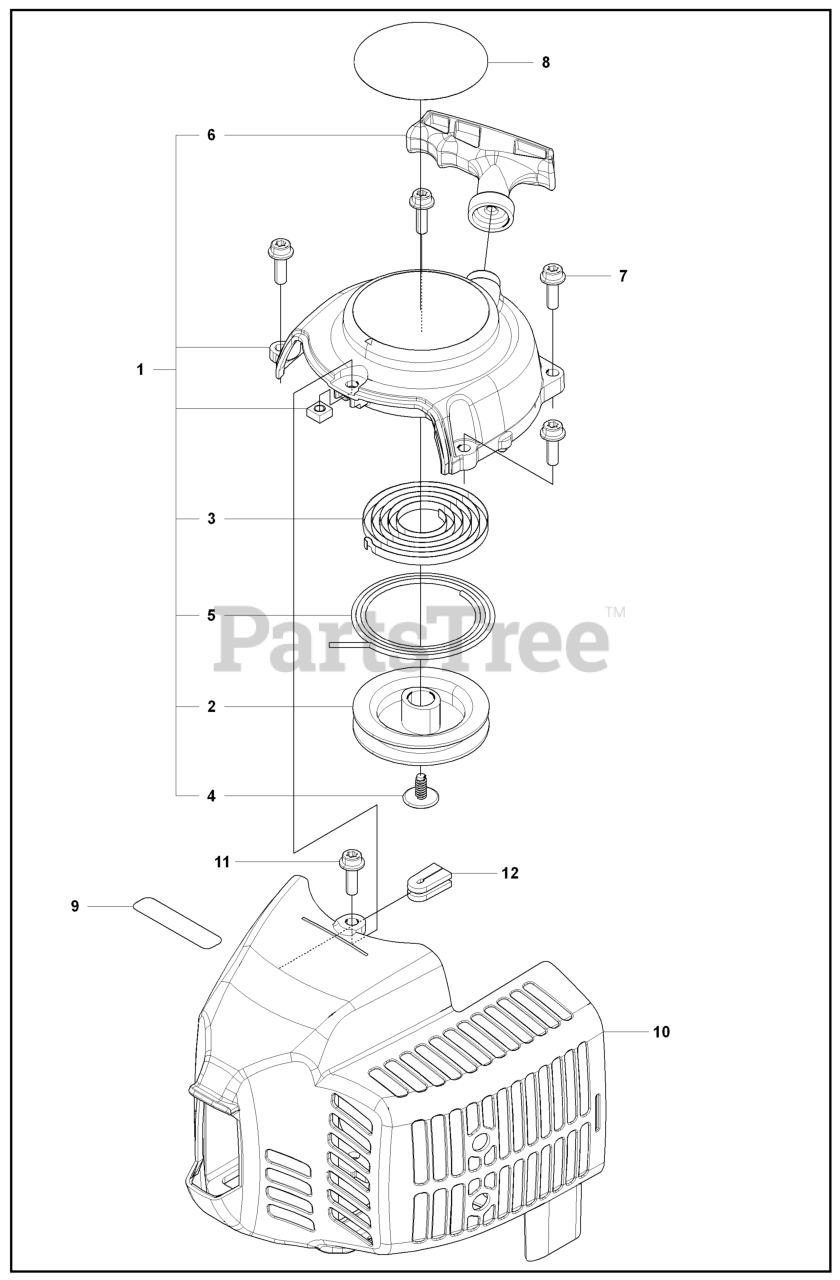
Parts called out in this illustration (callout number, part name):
1	RECOIL ASSY
4	SCREW
7	BOLT TORX
8	LABEL RECOIL
9	LABEL WARNING
10	COVER ENGINE
11	BOLT TORX
